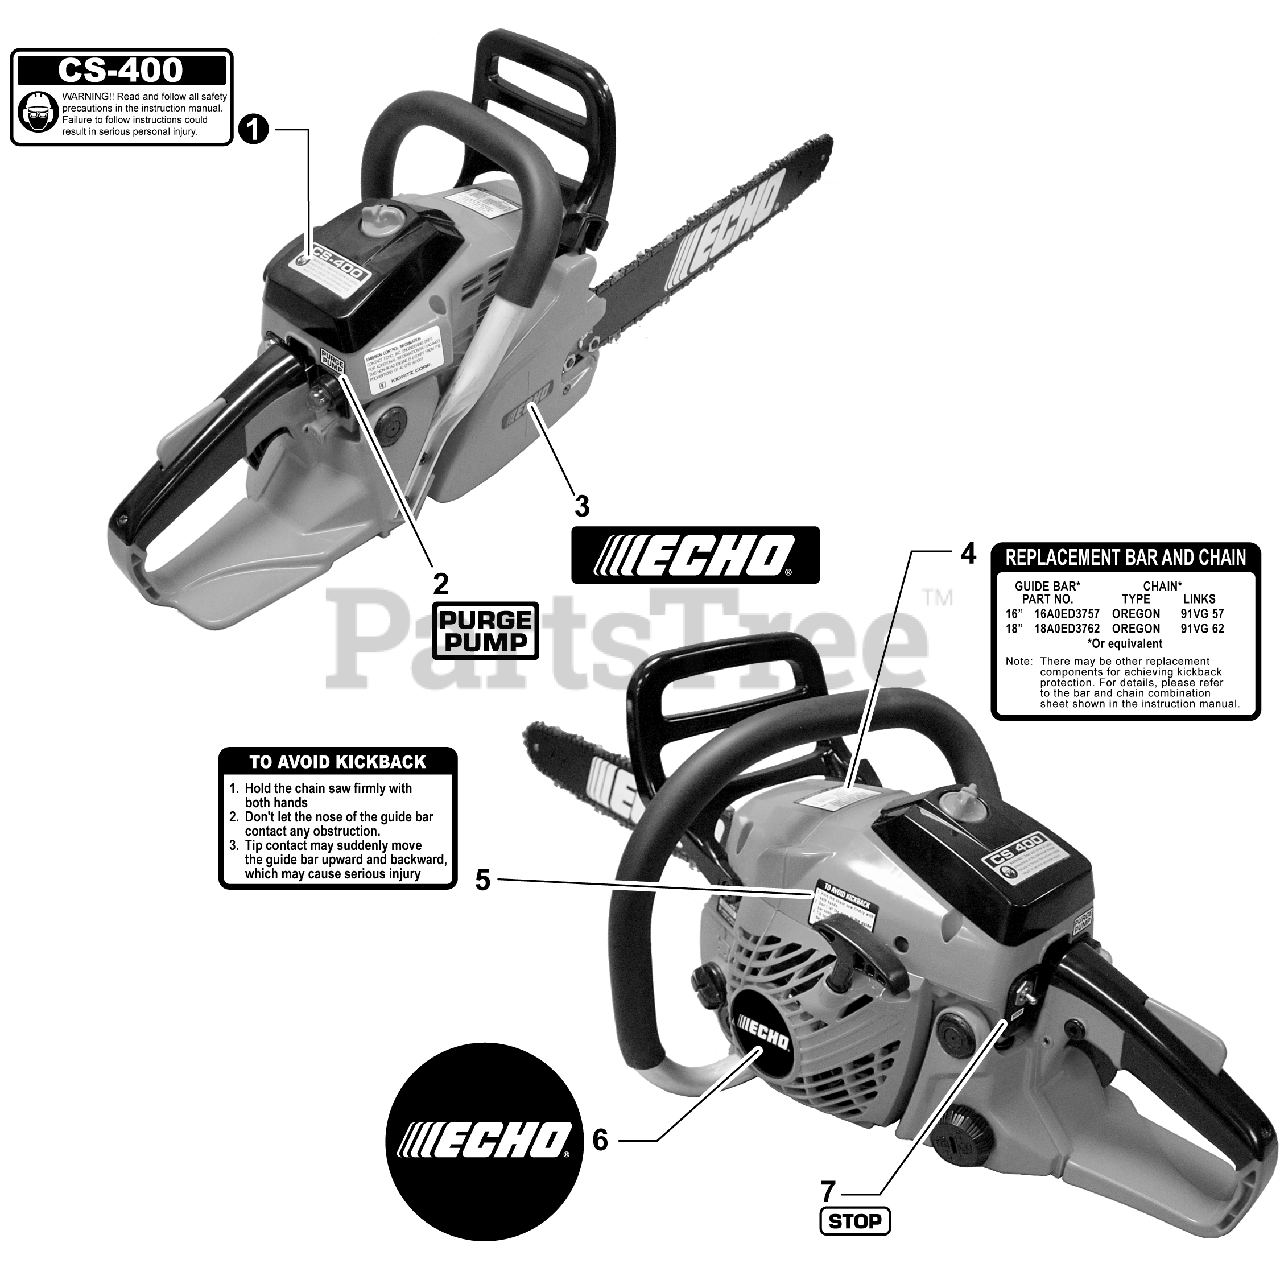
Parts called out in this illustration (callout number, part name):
1	LABEL - MODEL CS-400
2	LABEL, PURGE PUMP
3	LABEL, ECHO
4	LABEL, BAR & CHAIN
5	LABEL, UL - KICK BACK
6	LABEL, ECHO
7	LABEL, STOP
